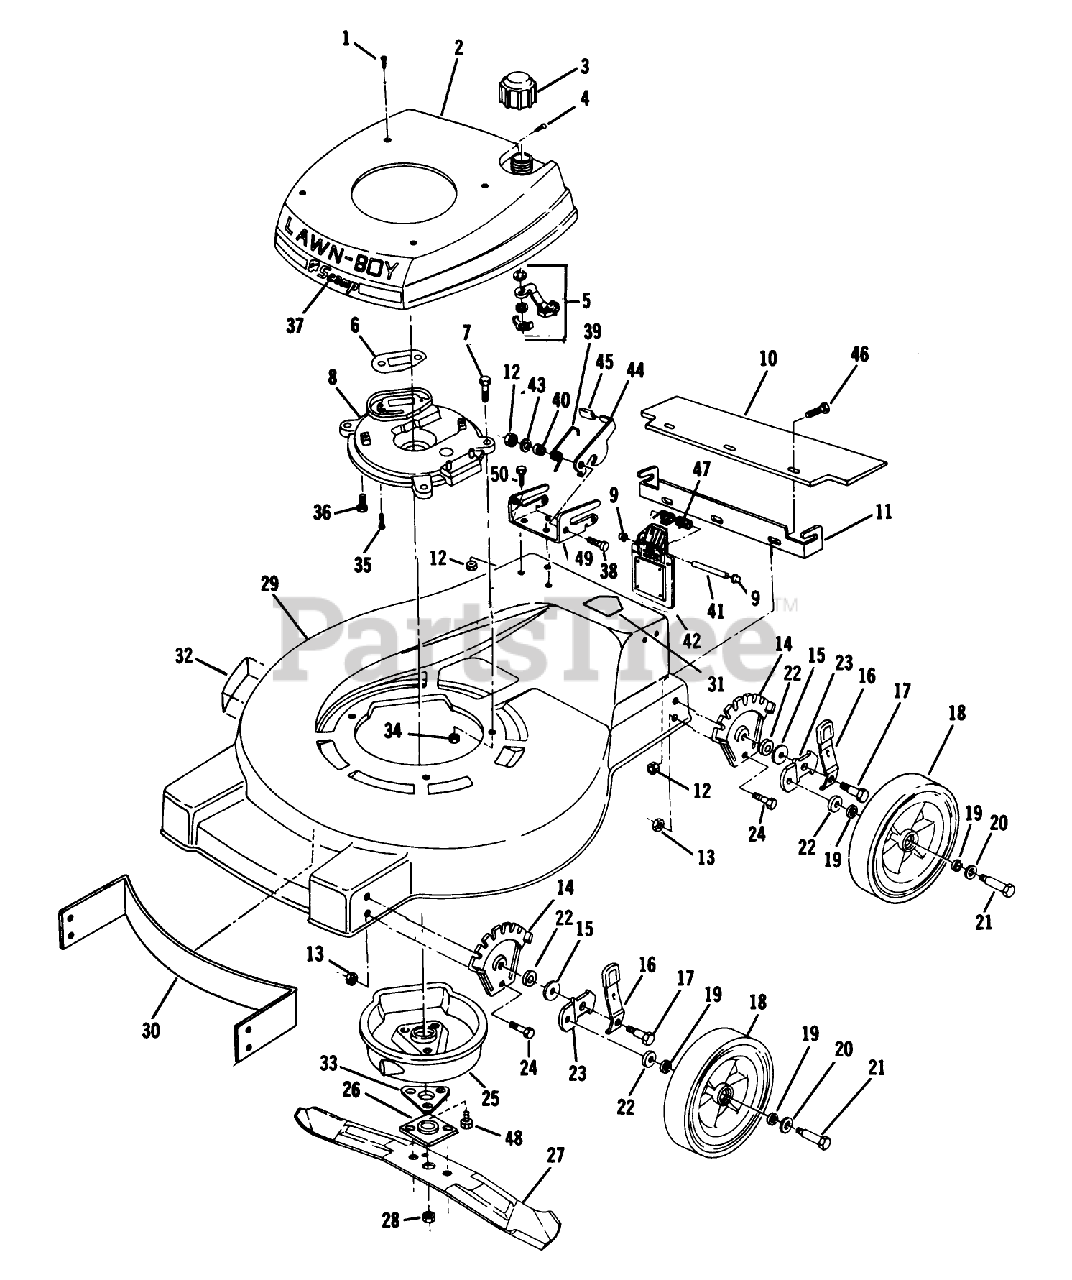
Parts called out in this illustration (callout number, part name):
1	SCREW LAWRENCE
3	FUEL CAP & INSERT
4	SCREW S
7	SCREW-HH
8	PLATE,MUFFLER F
10	SHIELD
12	LOCKNUT E
13	LOCKNUT
15	WASHER
16	KNOB & SPRING
17	BOLT
19	WASHER
20	SPACER
21	BOLT WHEEL
22	WASHER WROUGHT
26	PLATE AND COLLAR ASM
28	NUT-BLADE
33	SUPPORT F
34	NUT-LOCK F
35	SCREW V
39	SPRING
41	ROD ROCK/HDWE
47	SPRING ASOC
48	SCREW
